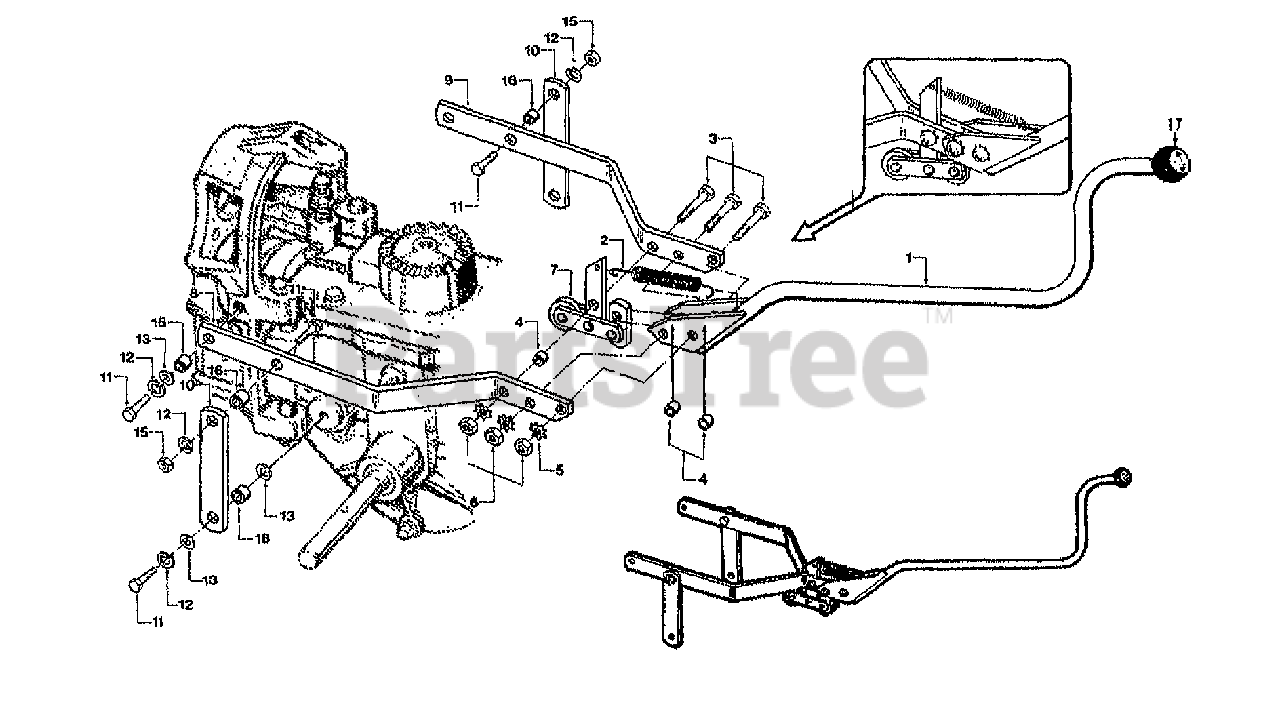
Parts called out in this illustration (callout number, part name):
1	ASSM-FOR/REV LEVER (INCL. KNOB W/DECAL)
2	SPRING-.436 X 3.25
3	SCR-HH 5/16-18X1.5 G5 ZP
4	BUSHING-.5X.316X.375 PM
5	WASHER-LK .312 EXT TOOTH
6	NUT-HEX 5/16-18 ZP
7	ASSM-ROLLER PAINT
8	YOKE-LH RED
9	YOKE-RH RED
10	YOKE-RED 2164
11	SCR-HH 3/8-16X1.0 G5 ZP
12	WASHER-LK .375 @ DEPL
13	WASHER-FLAT 3/8 SAE
14	THIS REF. NO. NOT USED
15	NUT-HEX 3/8-16 ZP
16	BUSHING-.5X.375X.3 (.300")
17	KNOB - NOT AVAIL. SEPARATELY. SEE REF. NO. 1
